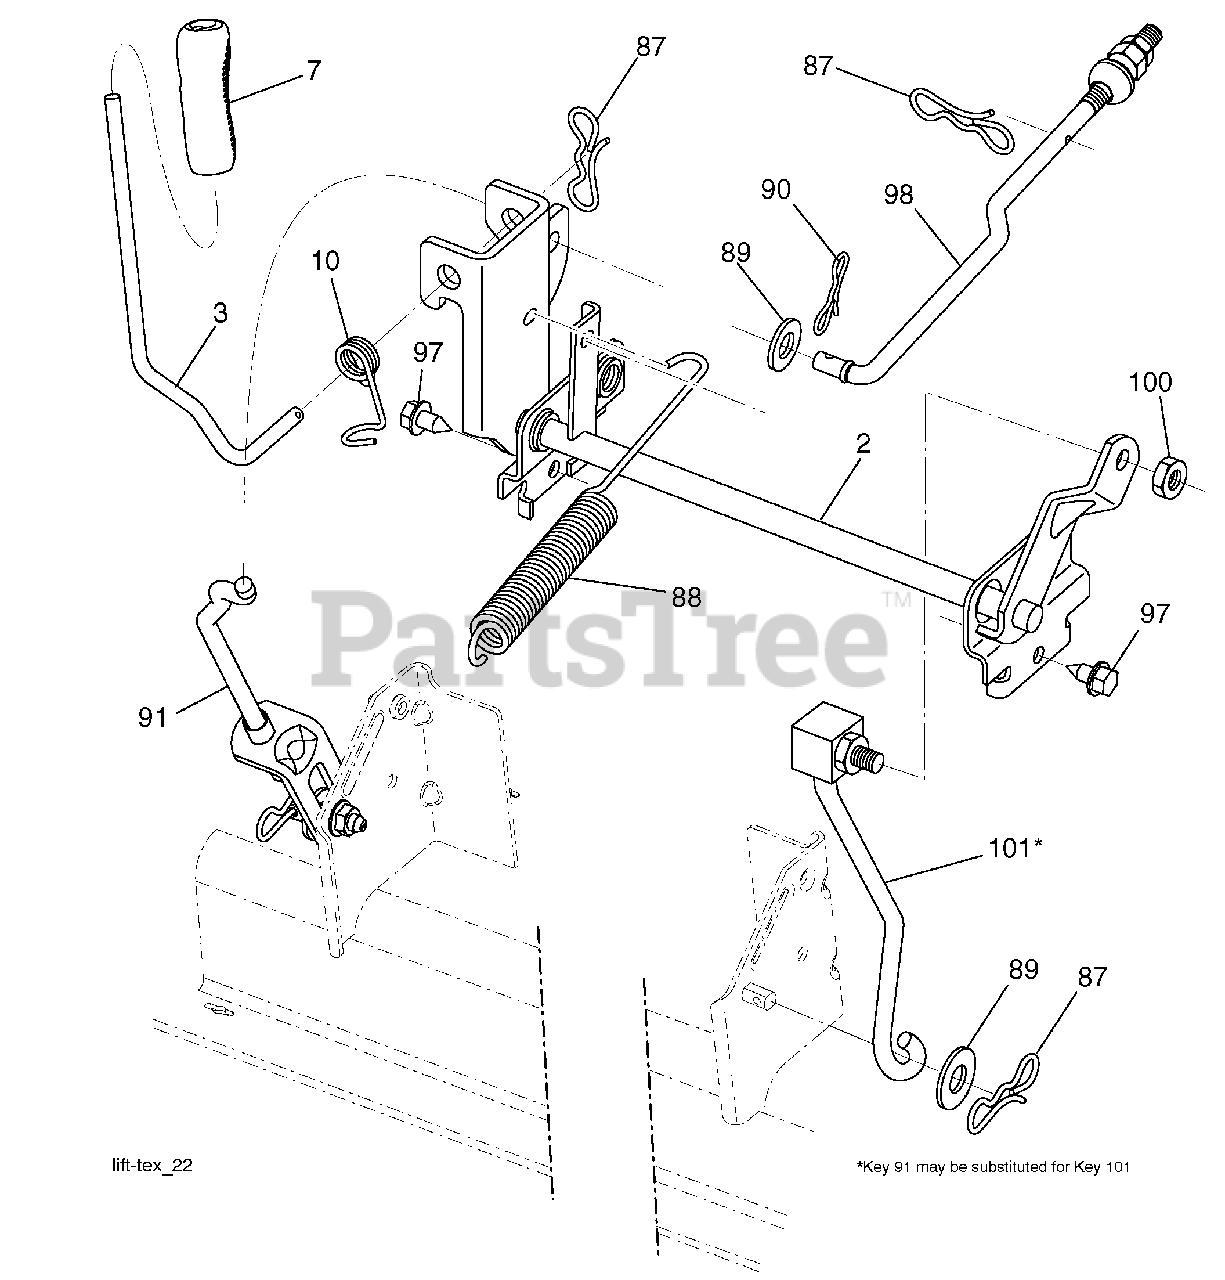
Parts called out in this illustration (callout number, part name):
2	Shaft Asm., Cross Lift
3	Lever Asm., Lift RH
7	Grip, Lever
10	Spring Torsion
87	Pin Cotter 7/16 Bow Tie Lock
88	Spring Lift Assist
89	Washer Clear Zinc
90	Pin Cotter 5/16 Bow Tie Lock
91	Link Lift Susp Mower Rear
97	Screw 3/8-16 x .75 Smgml Tap/R.Z
98	Link Lift Susp. Front Mower
100	Nut Centerlock 3/8 -16 unc
101	Link Asm. Lift Fixed
